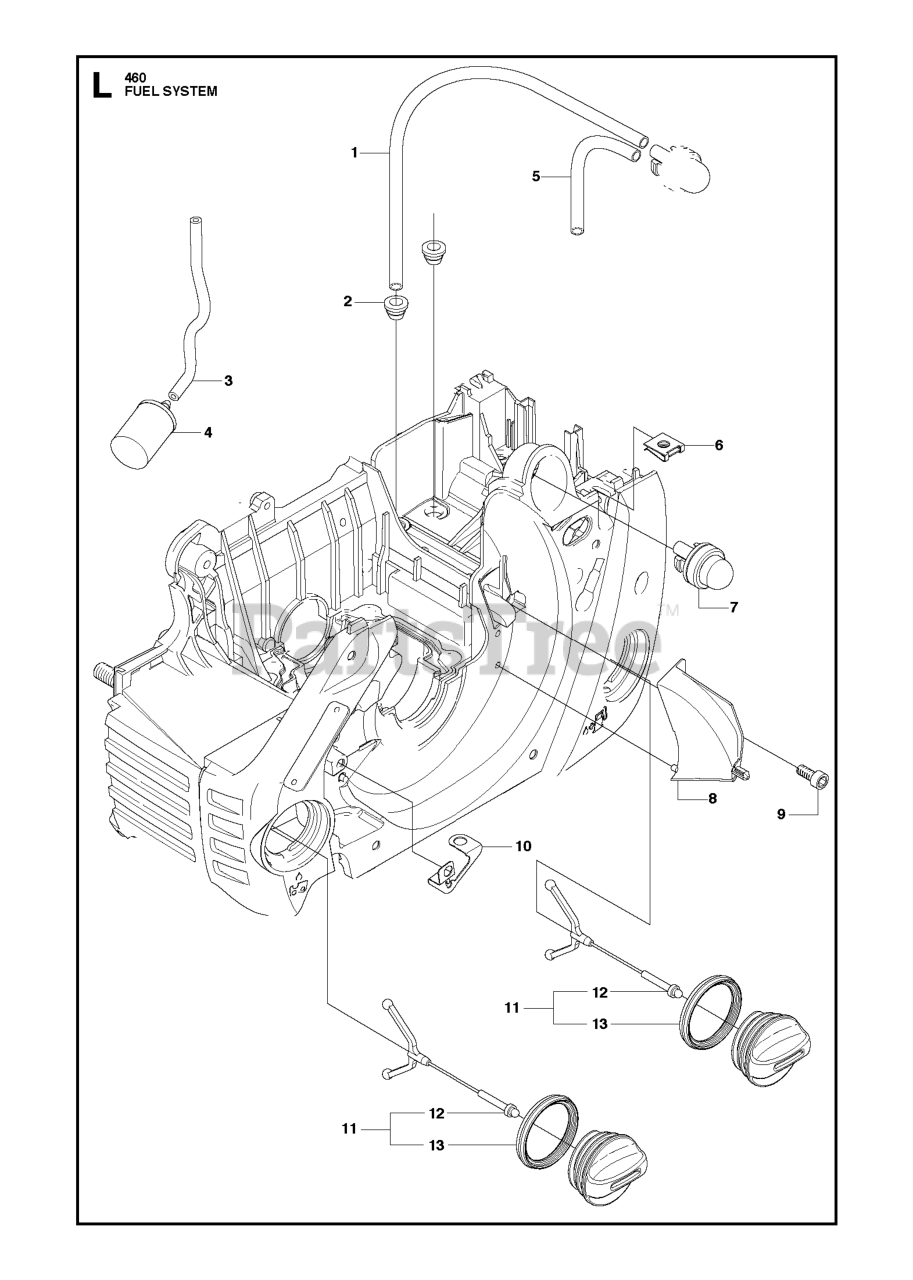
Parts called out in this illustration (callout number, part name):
2	FUEL TANK BUSHING
3	FUEL HOSE SPIRAL 300
4	RP FUEL FILTER
5	FUEL HOSE/38MM
7	AIR PURGE BUBBLE
8	AIR NOZZLE
10	SWITCH PLATE
11	TANK CAP
